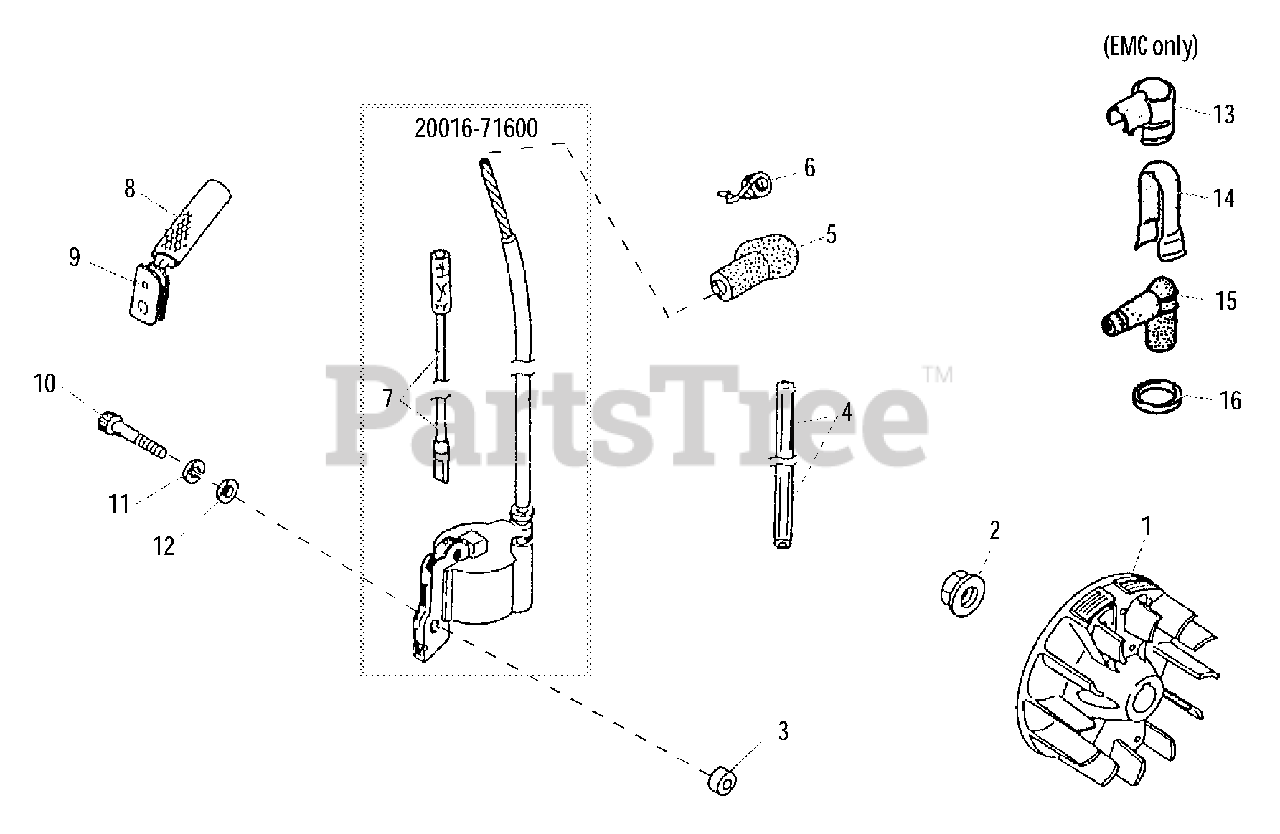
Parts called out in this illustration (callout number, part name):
1	FLYWHEEL
2	NUT - 8
3	INSULATOR
4	TUBE
5	CAP, SPARK PLUG
6	TERMINAL, SPARK PLUG CAP
7	LEAD - IGNITION
8	TUBE
9	GROMMET
10	SCREW - 4X26
11	LOCKWASHER - 4
12	WASHER - 4
13	CAP, SPARK PLUG
14	SHIELD
15	CAP, SPARK PLUG
16	SEAL, DUST
20016-71600	IGNITION COIL ASSY
